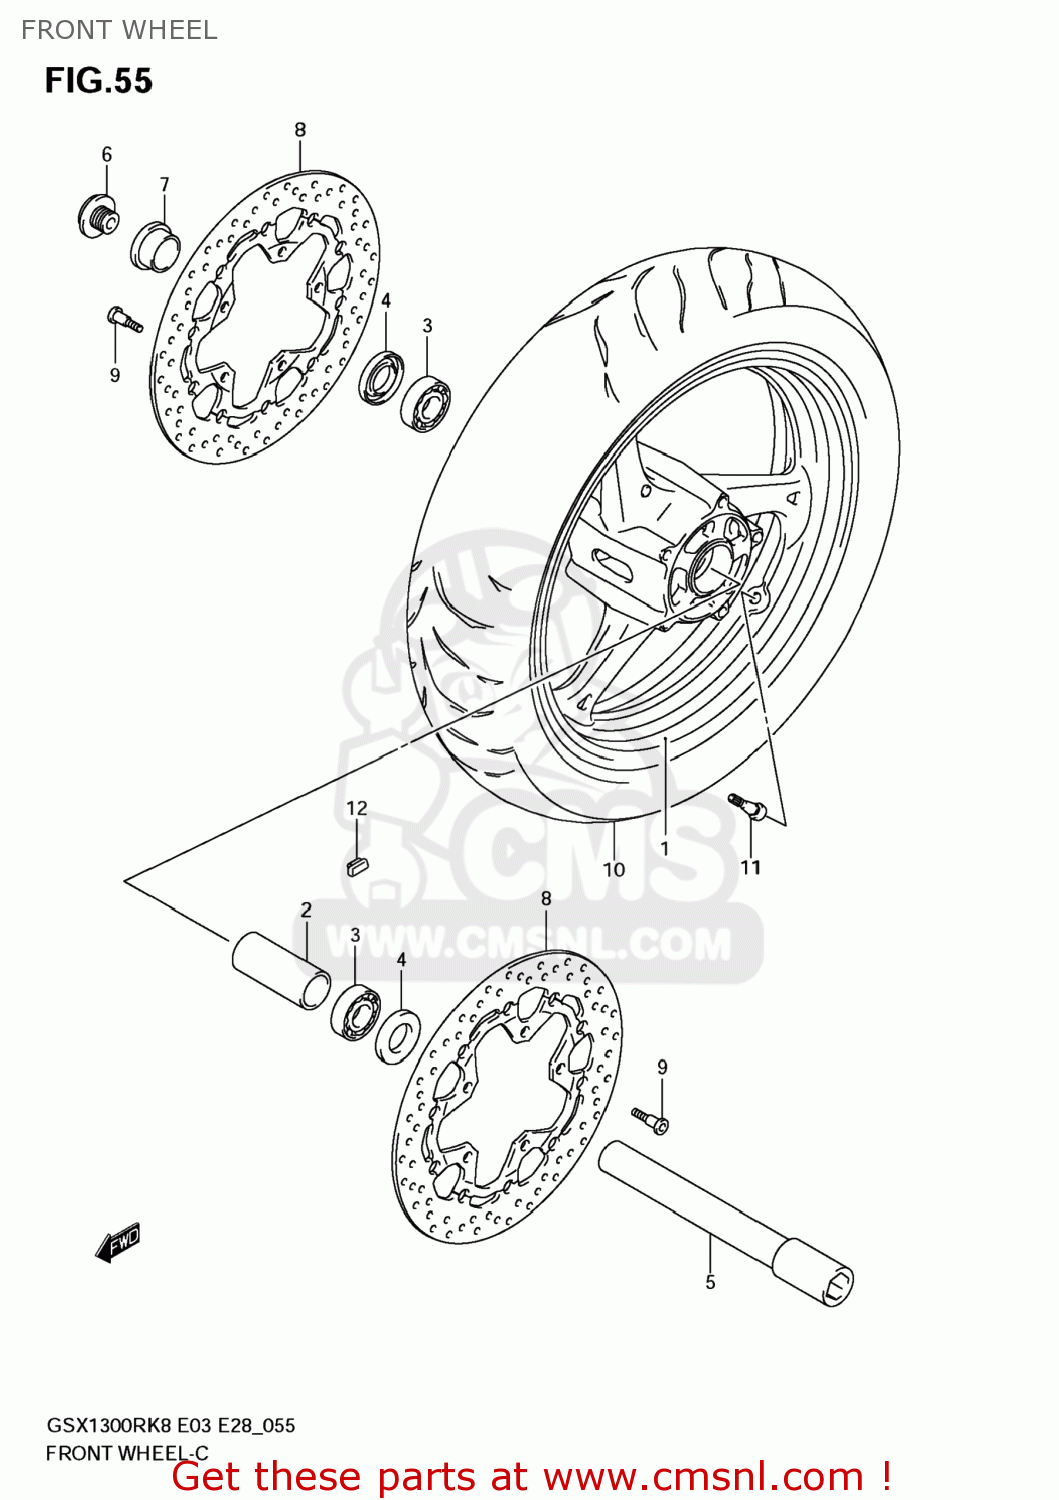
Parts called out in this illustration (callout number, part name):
1	WHEEL,FR(17M/CXMT3.50)
2	SPACER,FR HUB BEARING
3	BEARING(25X52X15)
4	SEAL,OIL(32X52X7)
5	AXLE,FR
6	BOLT,FRONT AXL
7	SPACER,FRONT A
8	DISC,FRONT BRA
9	BOLT(8X21)
10	TIRE,FRONT GSX
11	VALVE ASSY,WHEEL RIM(TR412)
12	BALANCER,WHEEL(10G)
